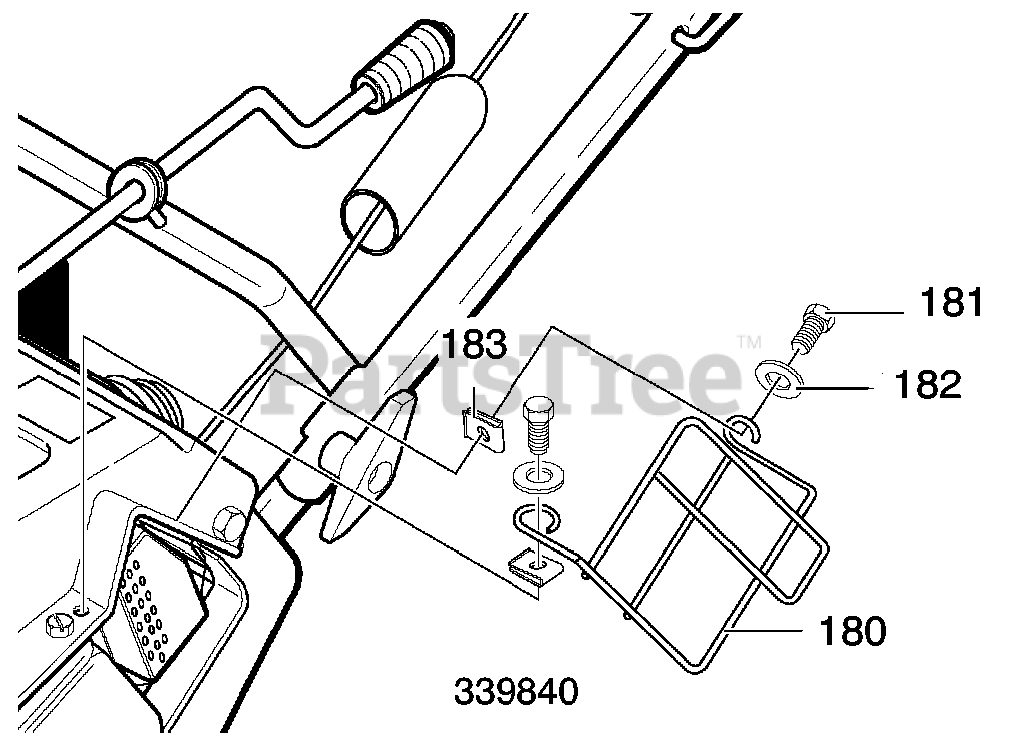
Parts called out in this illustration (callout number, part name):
180	GUARD, MUFFLER -EXPT
181	SCREW
182	WASHER, FLAT
183	NUT, 1/4-20 TINN
